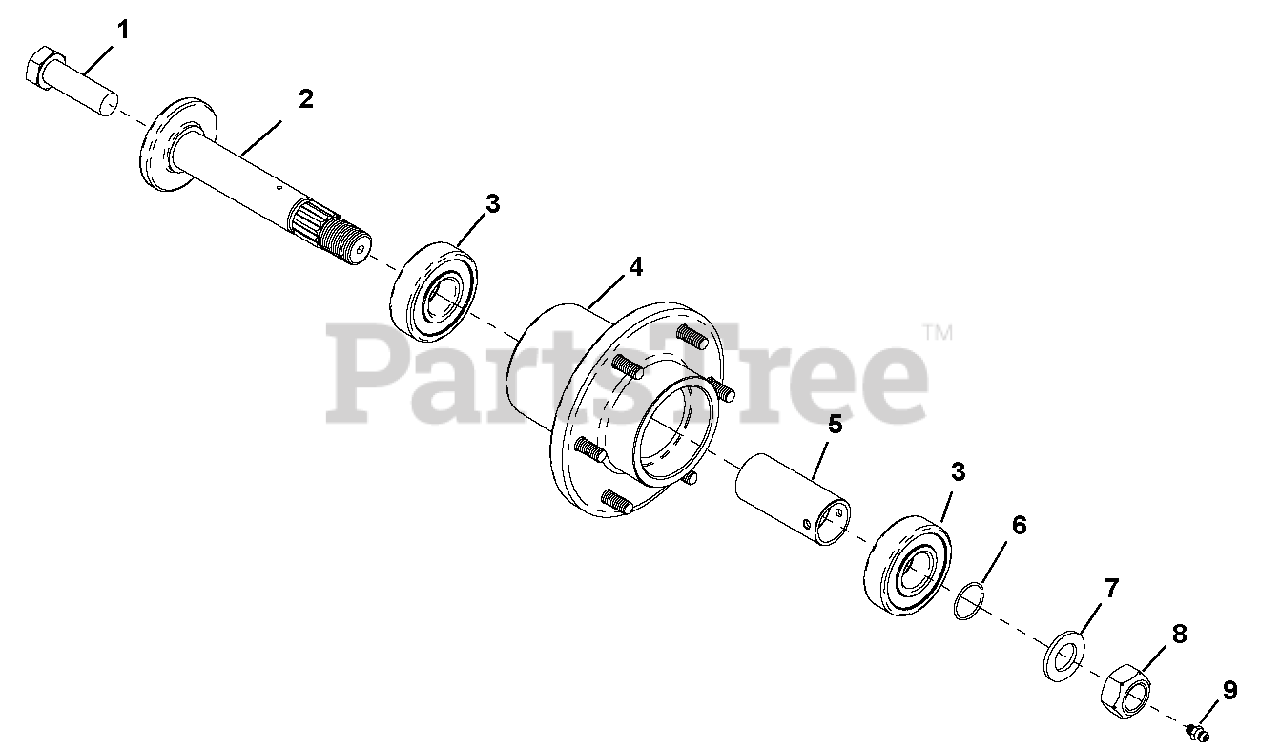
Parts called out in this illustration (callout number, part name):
1	Bolt, Blade .625-11 x 2.00 Hex Grade 8
2	Shaft, Spindle .75-16
4	Casting, Spindle w/Studs
5	Spacer, 1.25 x 1.00 x 2.78
6	Ring, Retainer
7	Washer, .75 x 1.3125 x .113
8	Nut, Lock .75-16 Crown
9	Fitting, .25-28 Straight Grease Zerk
